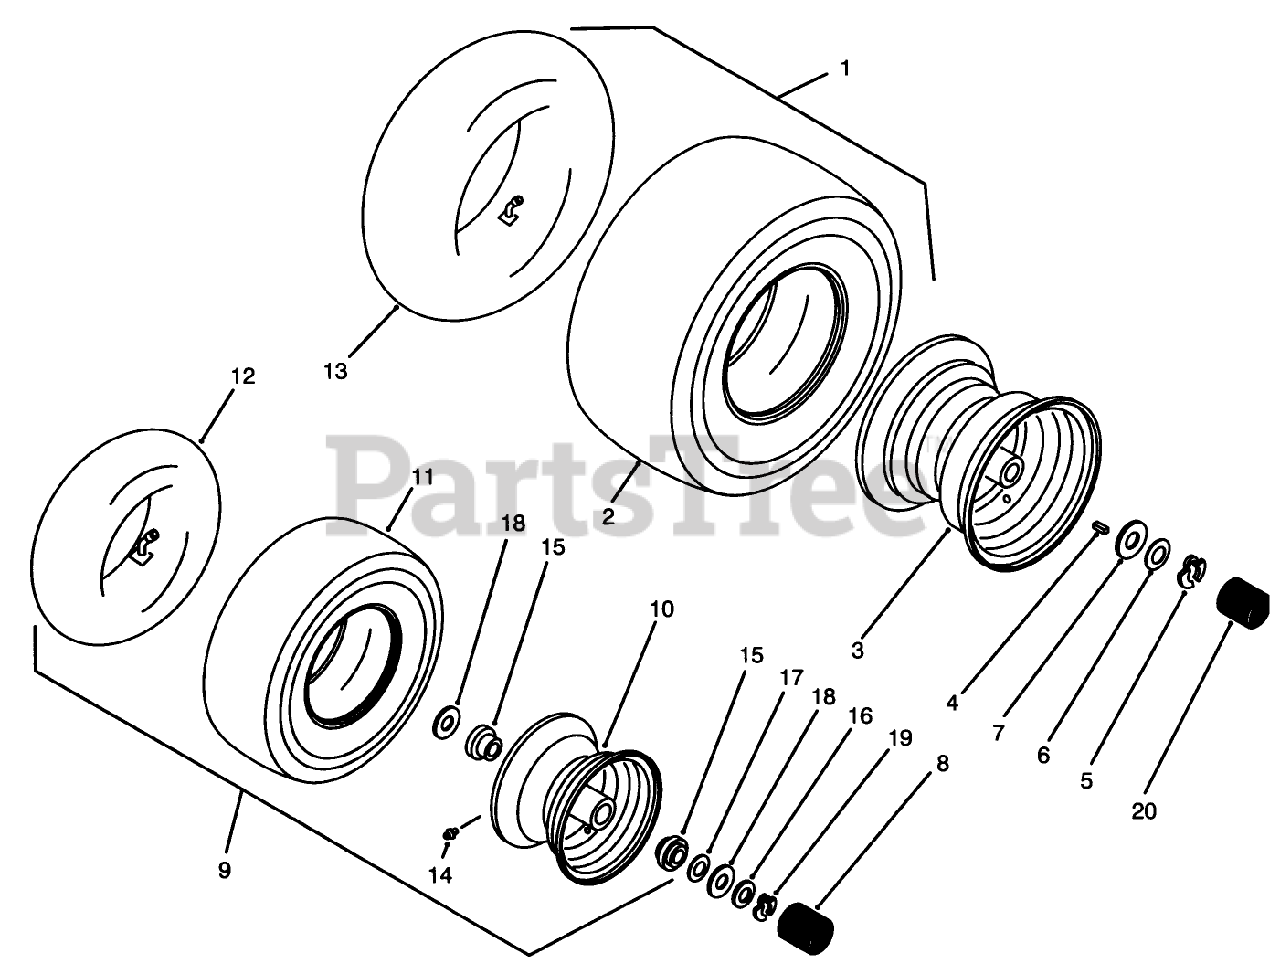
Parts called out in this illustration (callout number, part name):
5	RING-RETAINING
7	WASHER
13	TUBE-TIRE
14	ZERK-GREASE
15	BEARING-WHEEL
16	WASHER
17	WASHER-SHIM
18	WASHER-WHEEL
20	HUBCAP
